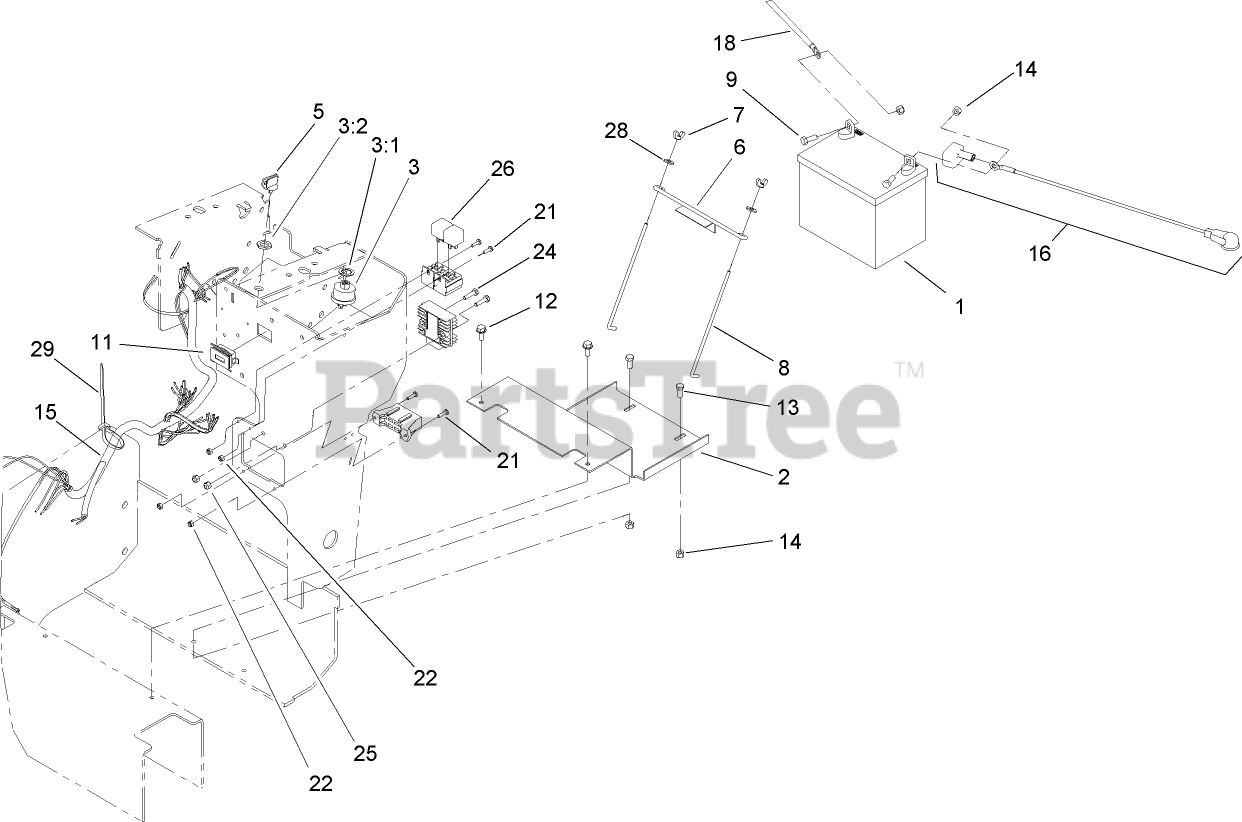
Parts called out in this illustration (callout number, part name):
1	BATTERY-DRY
2	BRACKET-BATTERY
3	Key Switch ASM
3:1	WASHER-TOOTH, INTERNAL
3:2	NUT-HH
5	KEY-IGNITION
6	HOLDDOWN-BATTERY
7	NUT-WING
8	RETAINER-BATTERY
9	SCREW-HH
11	HOURMETER
12	SCREW-HWHTF
13	SCREW-HH
14	NUT-LOCK, NI
15	HARNESS-WIRE
16	CABLE-POSITIVE
18	CABLE-BATTERY, NEGATIVE
21	SCREW-PPH
22	NUT-LOCK, NI
24	SCREW-HH
25	NUT-LOCK, NI
26	RELAY
28	WASHER-FLAT
29	TIE-CABLE
